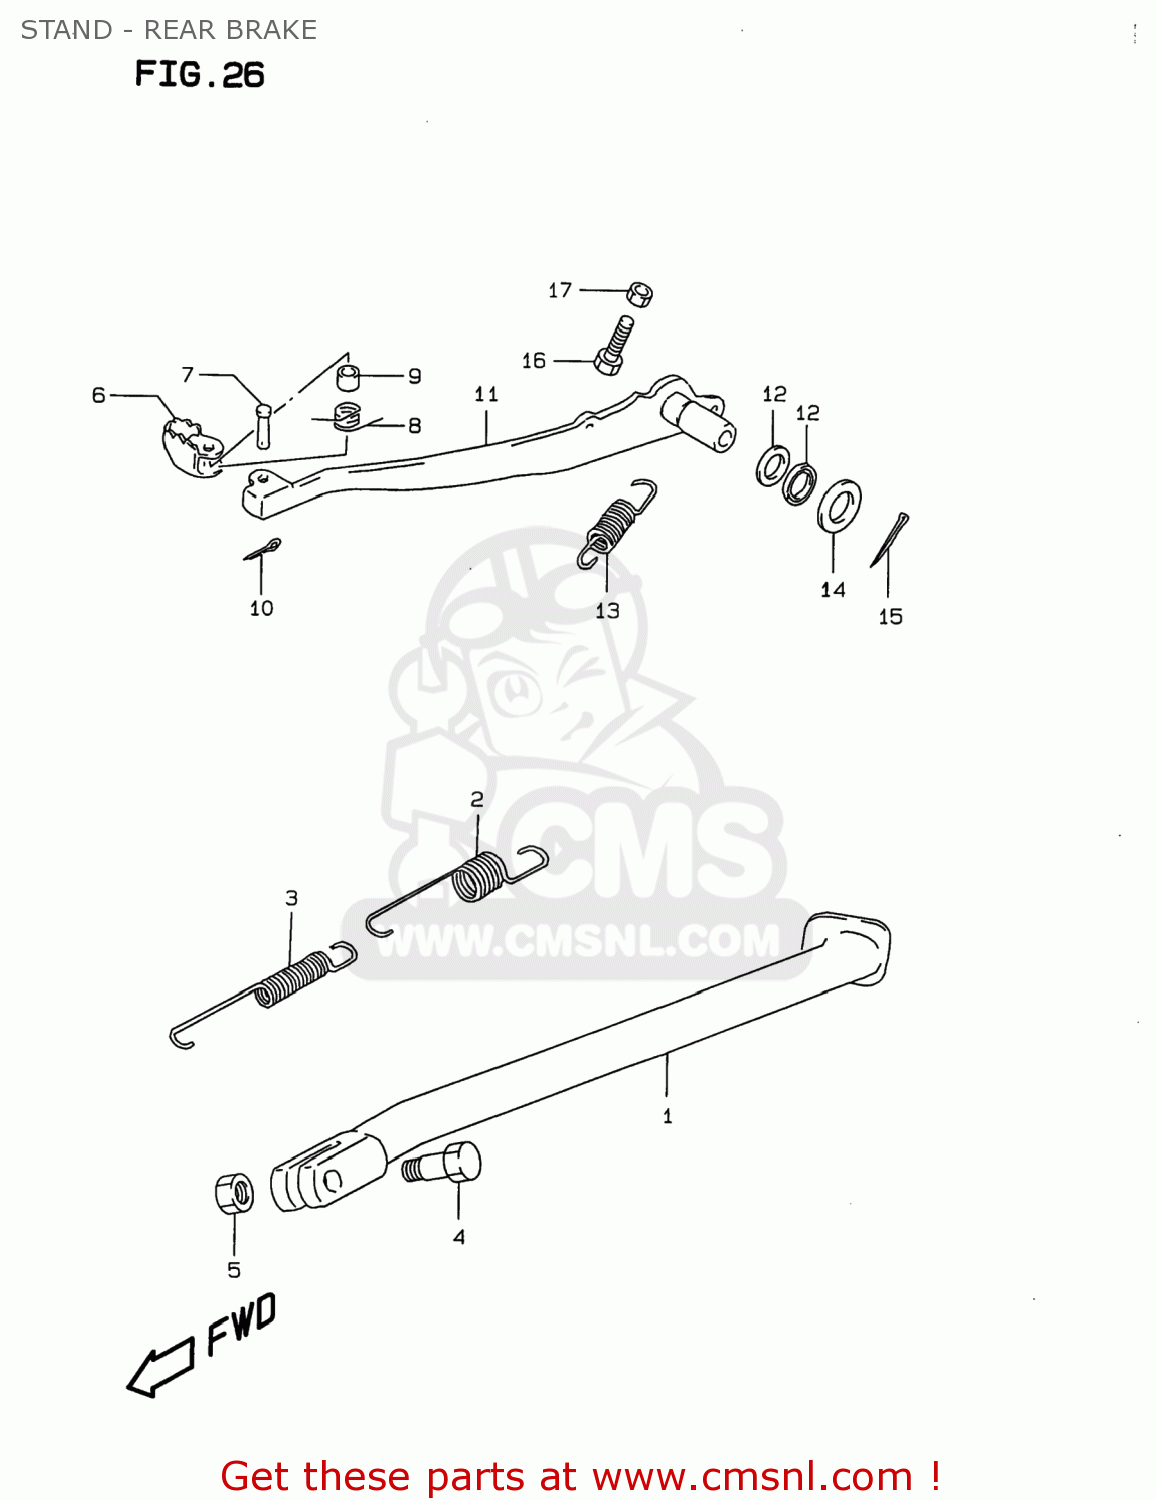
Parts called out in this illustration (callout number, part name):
1	STAND,PROP
2	SPRING
3	SPRING
4	BOLT(10X30)
5	NUT
6	PEDAL,BRAKE
7	PIN
8	SPRING
9	SPACER(6.5X9X6.5)
10	PIN
11	ARM,BRAKE PEDAL
12	SEAL,OIL(15X21X3)
13	SPRING
14	WASHER(15.5X26X2.3)
15	COTTER PIN
16	BOLT(6X23)
17	NUT 6MM
